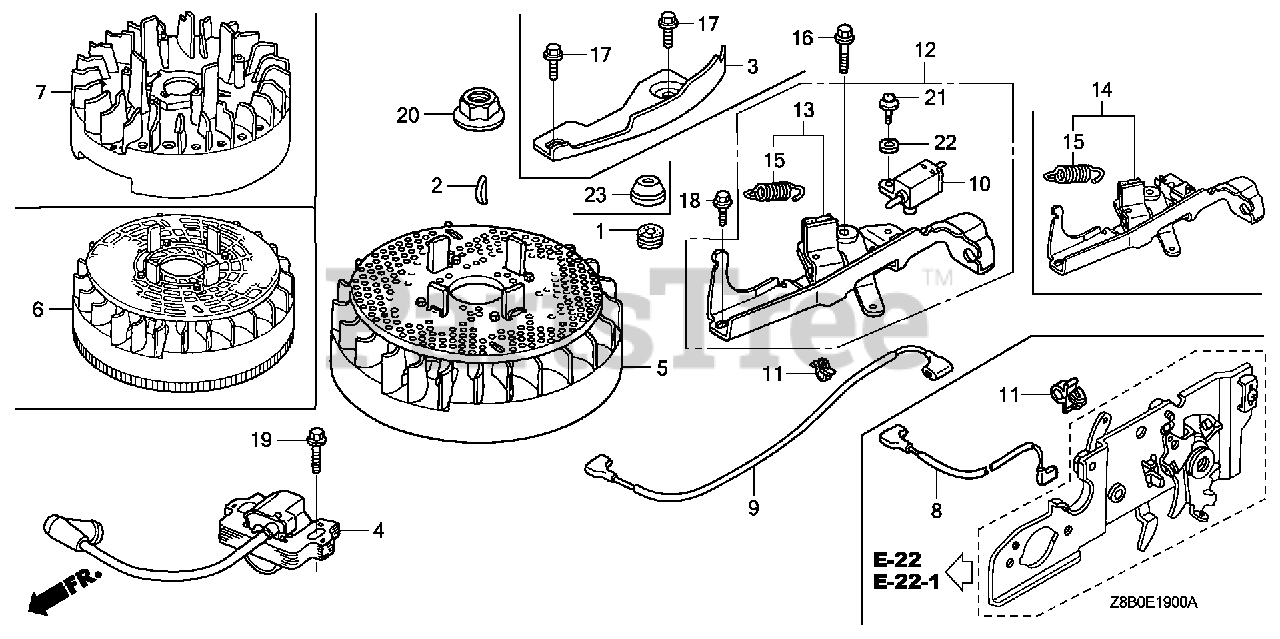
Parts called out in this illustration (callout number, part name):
2	KEY, SPECIAL WOODRUFF (25X18)
4	COIL ASSY., IGNITION (PHELON) (USE FOR F/W OF PHELON)
6	FLYWHEEL ASSY. (PHELON) (USE FOR IGN. COIL OF PHELON)
14	BRAKE SUB-ASSY.
15	SPRING, BRAKE LEVER
16	BOLT, FLANGE (6X23) (CT200)
18	BOLT, FLANGE (6X14) (CT200)
19	BOLT, FLANGE (6X23) (CT200)
19	BOLT, FLANGE (6X20) (CT200)
20	NUT, SPECIAL (14MM)
